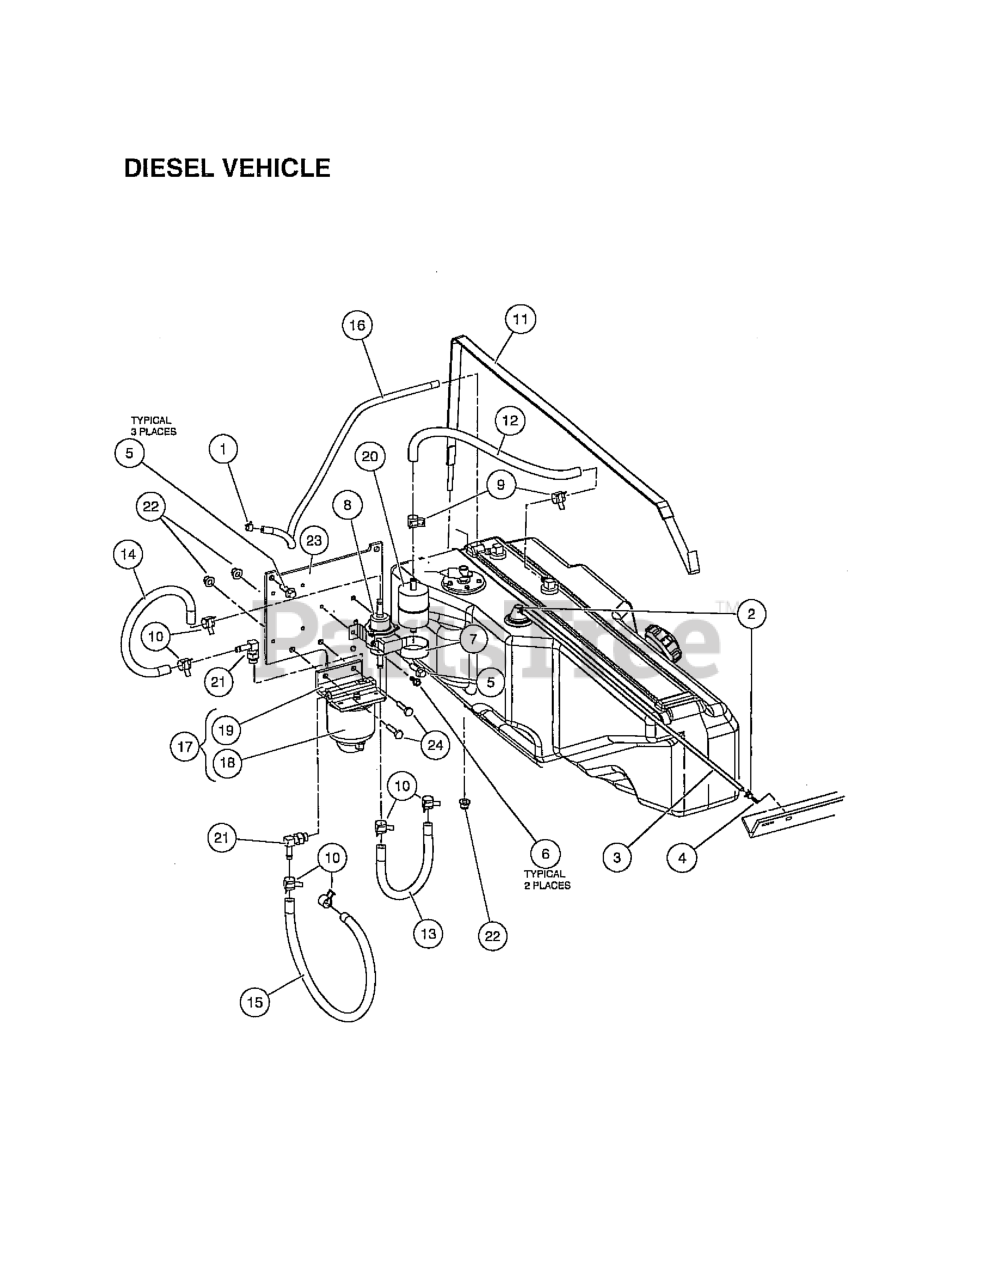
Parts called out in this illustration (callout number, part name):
1	CLAMP, GREEN HOSE
3	TUBE, CARBURETOR AIR VENT
5	SCREW-M8 X 1.25 30, TRI, HX F
6	SCREW, M6 X 16 TT HX FL HD
7	P-CLAMP, INSULATED 1.75 IN
8	PUMP, DIESEL FUEL ELECTRIC
9	CLAMP, HOSE, CTB 13MM
10	CLAMP, HOSE, CTB 14MM
11	STRAP, TANK, FUEL
12	HOSE, TANK TO PREFILTER DIESEL
13	HOSE, FUEL PREFILTER TO PUMP
14	HOSE, FUEL PUMP TO FILTER
15	HOSE, FUEL FILTER TO ENG
16	HOSE, FUEL RETURN
18	FILTER, WATER SEPARATOR
20	FILTER,FUEL
21	ADAPTER, 90-5 ORB, 5/16 TUBE
22	LOCK NUT, FLG M8 X 1.25 NYLON
23	PLATE, FUEL/OIL SYSTEM
24	BOLT, M8 X 1.25 X 30
